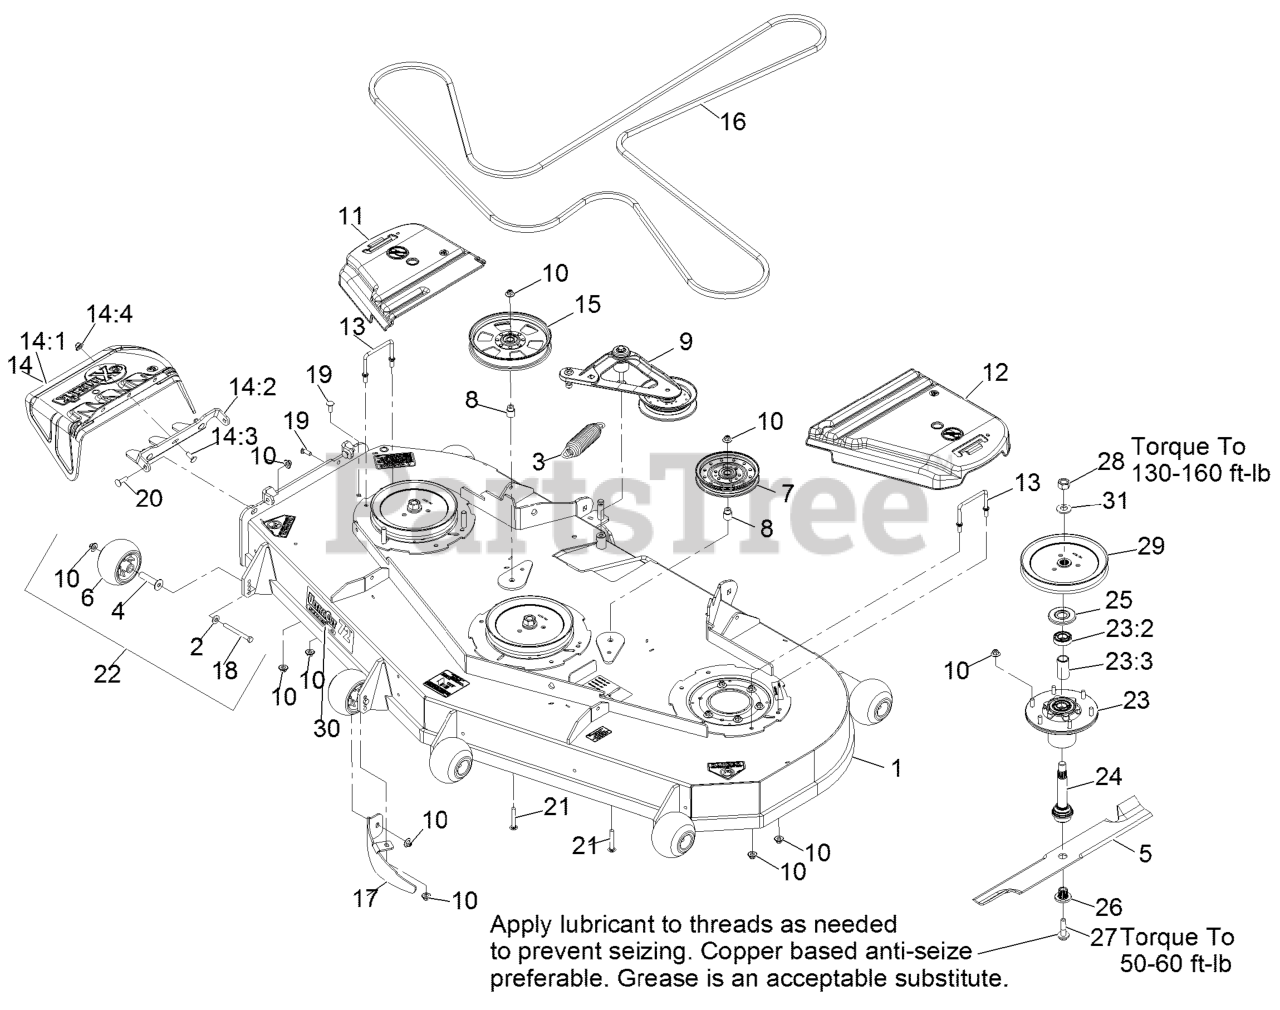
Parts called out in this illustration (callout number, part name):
1	ASM,DECK W/DECALS 724
2	WASHER-BELLEVILLE
3	SPRING-EXTENSION
4	AXLE, ROLLER
6	ROLLER-SCALP, ANTI
8	BUSHING-IDLER
9	DECK IDLER ASM
10	Nut-Nyloc 3/8-16 Flg
11	COVER-BELT, RH
12	COVER-BELT, LH
13	WIREFORM-COVER
14	ASM,DISCHARGE CHUTE
14:1	CHUTE,DISCHARGE
14:2	BRACKET,DISCHARGE CHUTE
14:3	SCREW-CARR
14:4	Nut-Nyloc 3/8-16 Flg
15	PULLEY-IDLER, FLAT
16	BELT-V
17	BAFFLE-DOGLEG, LZ72
18	SCREW-HH 3/8-16 X 3 3/4 GR 8
19	SCREW-CARR
20	Bolt-Carriage 3/8-16 X 1 1/4
21	SCREW-CARR
22	KIT, ANTI-SCALP ROLLER
23	ASM-CUTTER HSG WITH BEARINGS
23:2	BEARING-BALL
23:3	SPACER-BEARING
24	ASM-SPINDLE AND SEAL
25	GUARD,BEARING TOP .989
26	BUSHING,SPLINED
27	SCREW,SEMS 1/2-20 X 2.19
28	NUT-HEX
29	SHEAVE,BLADE DRIVE 8.74
30	DECAL,ULTRACUT 72 SERIES
